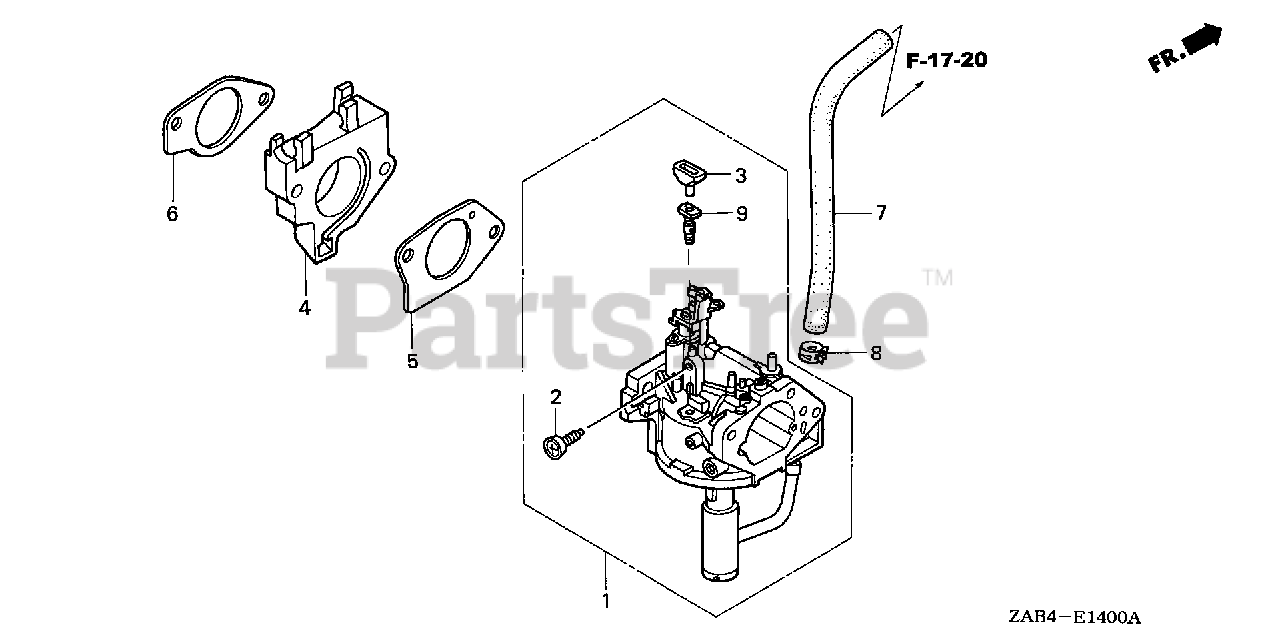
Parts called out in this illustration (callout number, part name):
1	CARBURETOR ASSY. (BEL5D A)
2	SCREW, THROTTLE STOP
3	COLLAR, SET
4	INSULATOR, CARBURETOR
5	GASKET, CARBURETOR
6	GASKET, INSULATOR
7	HOSE, FUEL (B)
8	CLIP, FUEL HOSE
9	JET, PILOT (#45)
